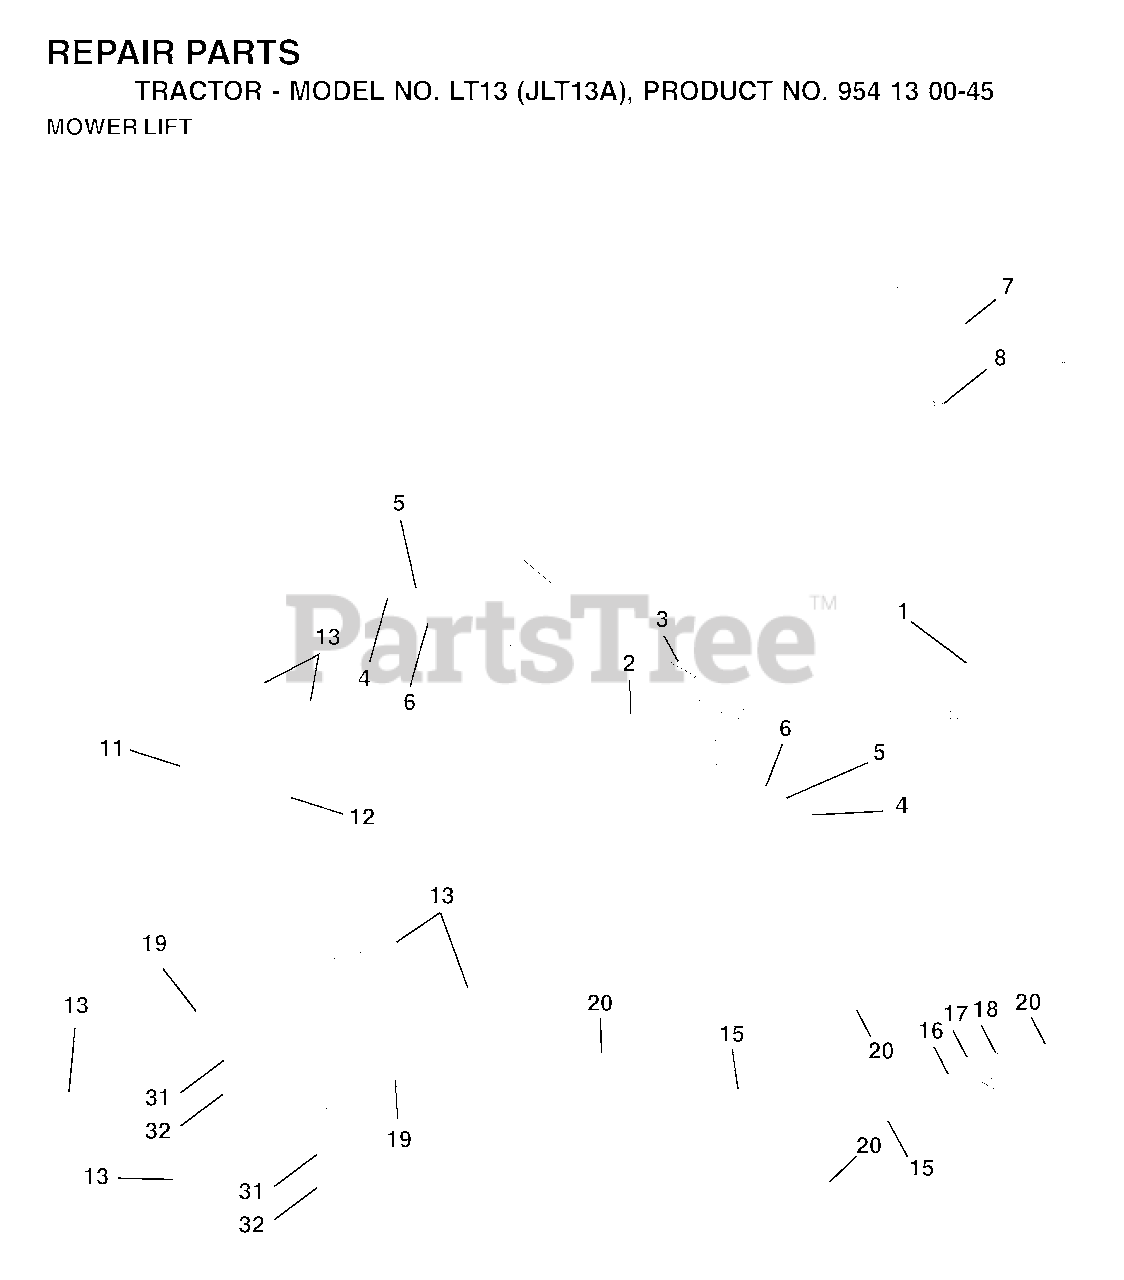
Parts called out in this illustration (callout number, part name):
1	WIRE ASM INNER W/ PLUNGER LT
2	SHAFT ASM R HANDLE
3	PIN GROOVE
4	RETAINING RING LT
6	BEARING.NYLON
7	GRIP
8	PLUNGER BUT KIT
11	LINK LIFT LH
12	LINK LIFT RH
13	RETAINER-SPRNG RB
15	LINK.SUSPENSION.FRONT
16	NUT
17	TRUNION
18	NUT
19	ARM.REAR.SUSPENSION
20	SPRING RETAINER
31	BEARING.PIVOT.LIFT
32	NUT CROWNLOCK 3/8-24
